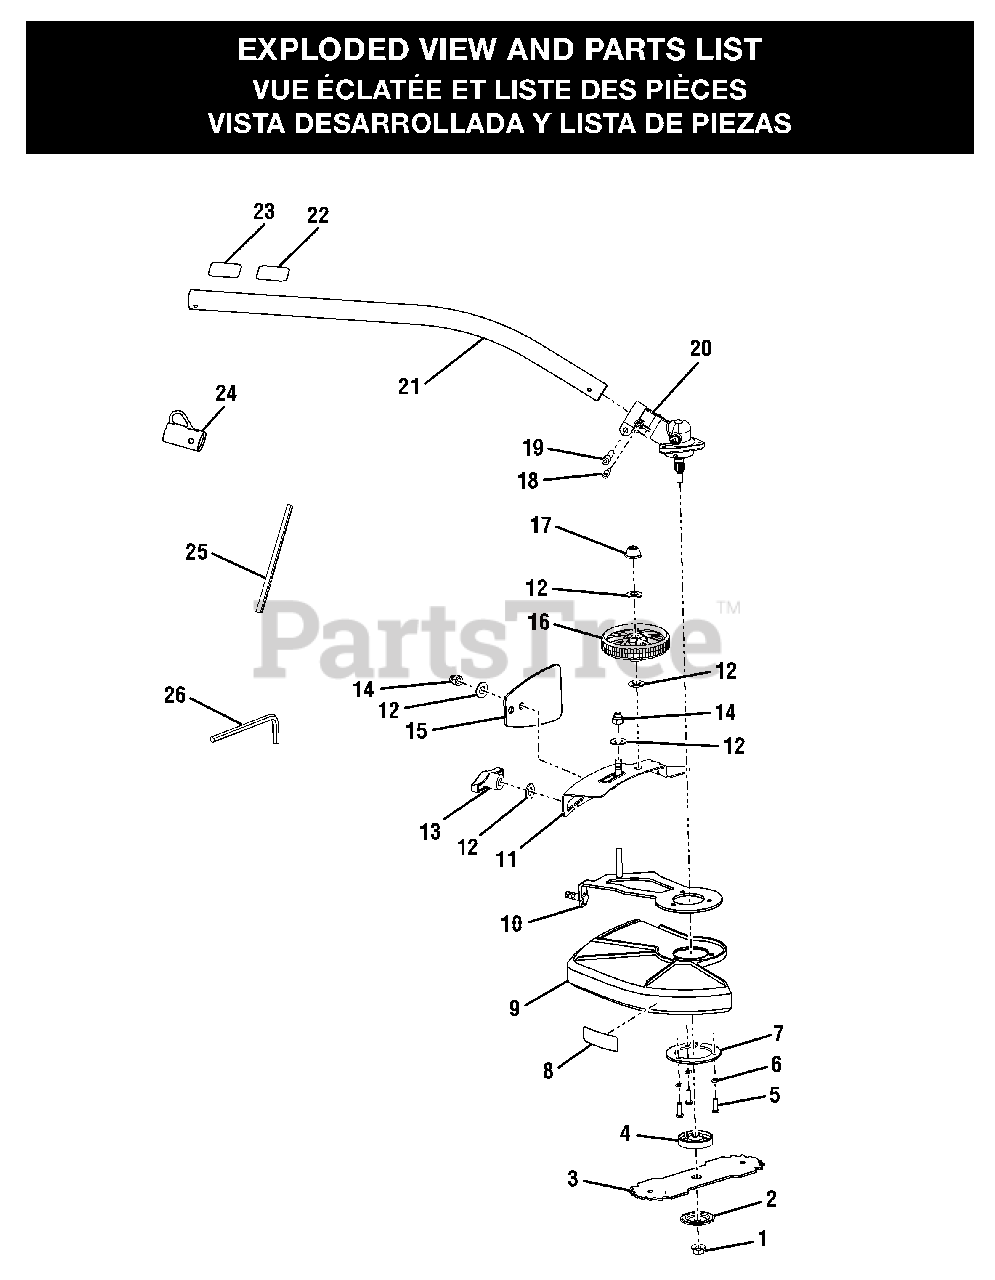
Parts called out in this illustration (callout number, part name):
1	Blade Nut (M8, LH)
2	Cupped Washer
4	Flange Washer
5	Screw (10-24 x 5/8 in. Hex Hd.)
6	Lock Washer (5 mm)
7	Ring Washer
8	Warning Decal
9	Blade Guard
10	Main Frame
11	Wheel Frame
12	Washer (10 mm)
13	Adjusting Knob with Hex Nut
14	Hex Nut with Nylon Cap (5/16-18)
15	Debris Flap
16	Guide Wheel
17	Push Nut (10 mm)
18	Screw (10-24 x 5/8 in. Hex Socket Hd.)
19	Screw (1/4-20 x 1-1/4 in., Hex. Socket Hd.)
20	Gear Head Assembly
21	Drive Shaft Assembly
22	Label, Logo
23	Warning Label
24	Hanger Cap
25	Holding Pin
26	Hex Wrench
